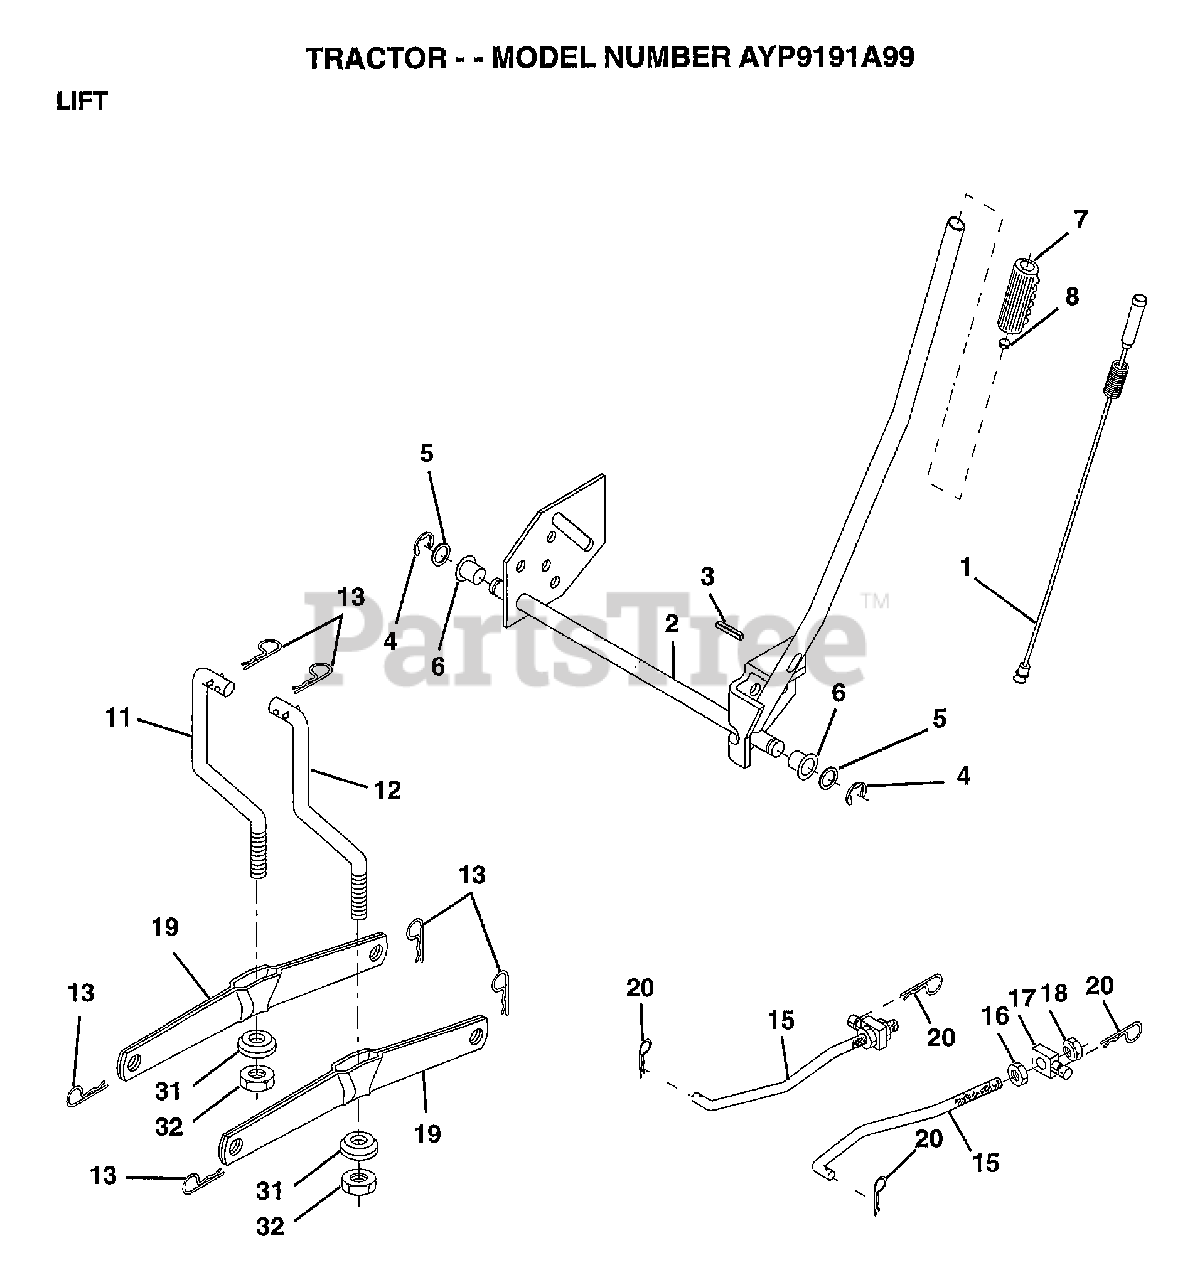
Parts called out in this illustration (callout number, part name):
1	WIRE ASM W.SPRING
2	"SHAFT ASM LIFT,RH"
3	PIN-GROOVE LT
5	WASHER
6	NYLON BEARING
7	GRIP
15	LINK.FRONT
16	NUT
17	TRUNION
18	NUT.LK.W/WSH.1/2.
19	ARM SUSP REAR
20	RETAINER SPRING
31	BEARING PVT LH
32	NUT.CROWNLOCK.3/8
